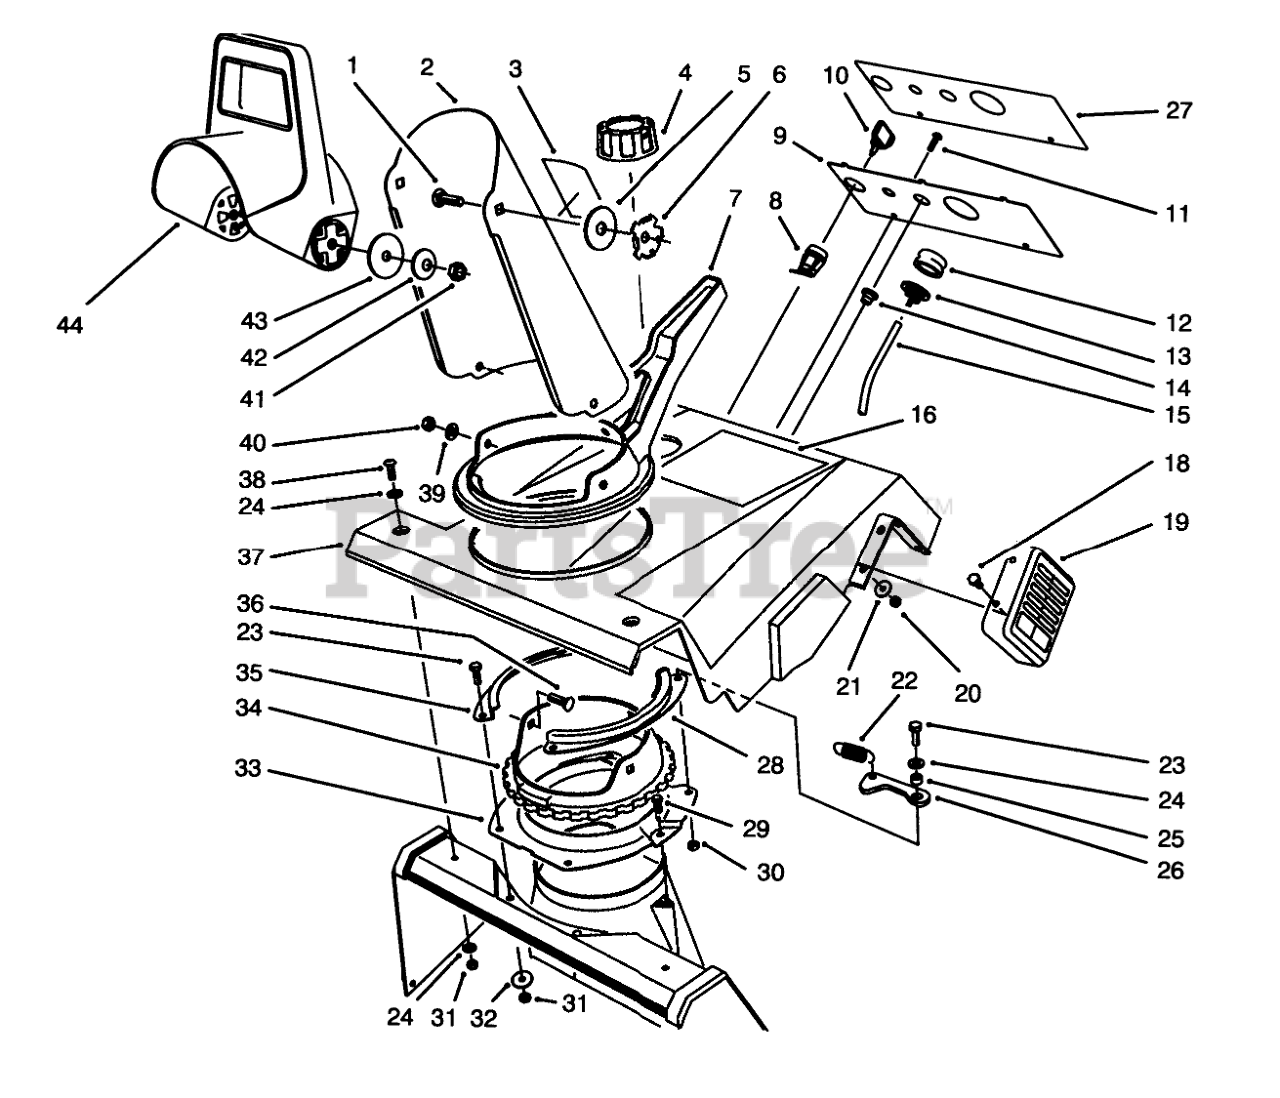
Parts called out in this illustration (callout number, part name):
1	SCREW-CARR
2	Chute
3	Decal-Danger
4	CAP-FUEL ASM
5	WASHER-RUBBER
6	PLATE-FRICTION
7	CHUTE - HANDLE
8	SWITCH
9	Panel-Control
10	KEY-IGNITION
11	SCREW-SHWH, THREAD FORMING
12	BULB-PRIMER
13	BODY-PRIMER
14	GUIDE-ROPE, STARTER
15	HOSE-PRIMER
16	DECAL - CCR1000
18	SCREW-HWH
19	Guard-Muffler
20	NUT-LOCK, NI
21	WASHER-FLAT
22	OBS DETENT SPRING
23	SCREW-HH
24	WASHER-FLAT
25	SPACER-BLADE, ROTOR
26	DETENT
27	DECAL - CONTROL PANEL
28	Retainer-Chute Ring
29	SCREW-PLASTITE
30	NUT-LOCK, NI
31	NUT-LOCK, NI
32	WASHER-FLAT
33	Ring-Chute Support
34	GEAR RING, CHUTE
35	Retainer-Chute Ring
36	SCREW-CARR
37	UPPER SHROUD
38	SCREW-PPH
39	WASHER-FLAT
40	NUT-KEPS
41	NUT-LOCK, NI
42	WASHER-BELLEVILLE
43	WASHER-FLAT
44	CHUTE-DEFLECTOR
